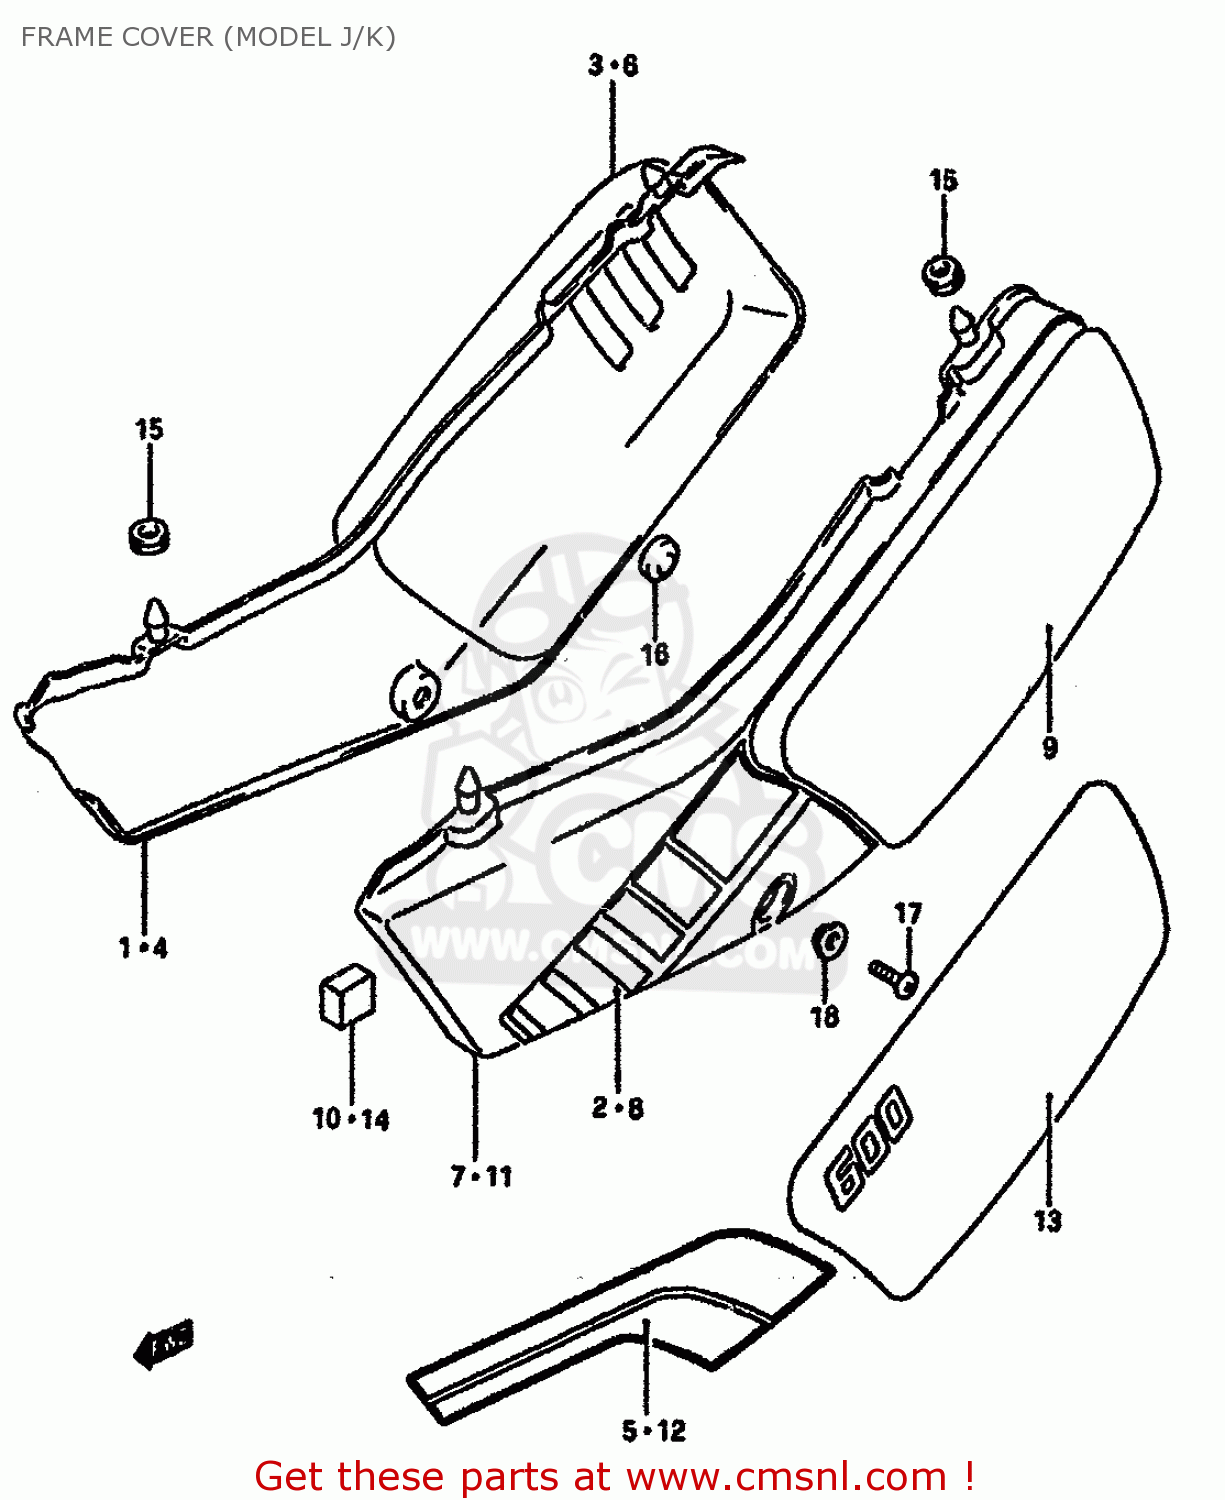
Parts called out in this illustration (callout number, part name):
1	COVER, SIDE RH (BLUE)
2	TAPE,FRAME COVER RH
3	TAPE, REAR RH (BLUE)
4	COVER,FRAME RH (BLUE)
5	TAPE,FRAME COVER FRONT RH
6	TAPE,FRAME COVER REAR RH
7	COVER, SIDE LH (BLUE)
8	TAPE, FRONT LH
9	TAPE, REAR LH (BLUE)
10	CUSHION,FRAME COVER
11	COVER,FRAME LH (BLUE)
12	TAPE,FRAME COVER FRONT LH
13	TAPE,FRAME COVER REAR LH
14	CUSHION,FRAME COVER
15	CUSHION,SIDE COVER BOSS
16	CUSHION
17	SCREW 6X12
18	WASHER
